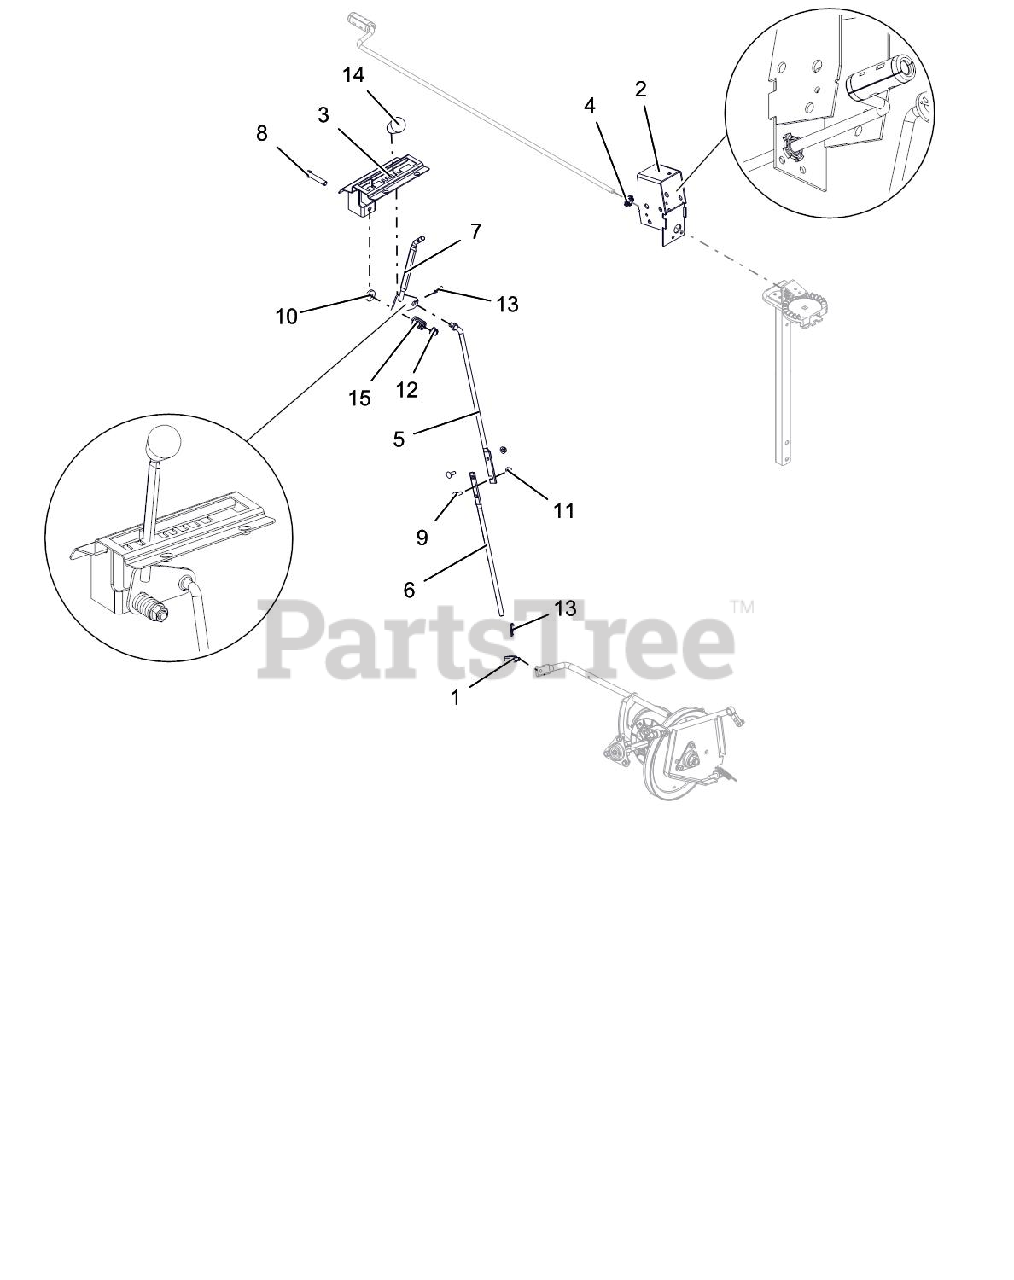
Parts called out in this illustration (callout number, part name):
1	PIVOT,SHIFT ROD .375-16(TRUNN)
2	WELDMENT, BRACKET INTERLOCK
3	WELDMENT, DETENT PLATE-COMPACT
4	CRANK BUSHING, NYLON CHUTE BK
5	ROD, SHIFT - UPPER
6	ROD, SHIFT - LOWER(SMALL DASH)
7	LEVER, CONTROL-SHIFT(WELDMENT)
8	@BLT-HEX .38-16X2.00 GR5 YWZC
9	@BLT-RDHDSQNK .25-20X.75 G5YZ
10	WSHR-FL-STL .406X1.00X.188 YWZ
11	@NUT-LK-CTR-FLG .25-20 YWZC
12	@NUT-LK-TOP-FLG .38-16 YWZC
13	PIN-HAIR INT .08X.18X1.18 YWZC
14	KNOB,SOFT TEARDROP,PUSH-ON BLK
15	SG-COMP .125X.781X1.250
